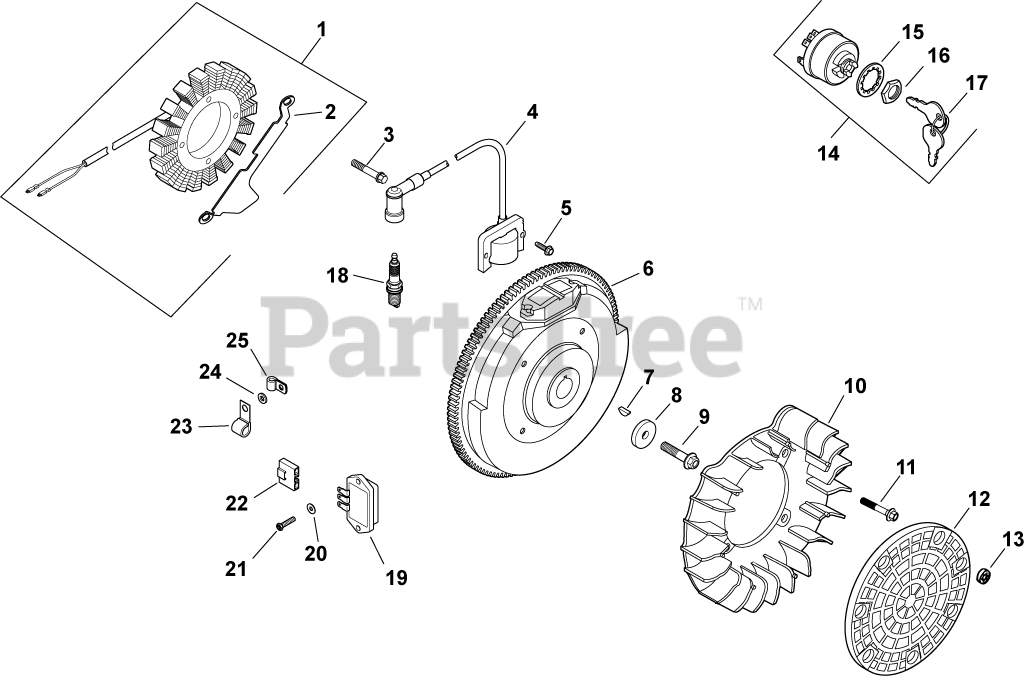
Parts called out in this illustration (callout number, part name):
1	KIT, 15 / 20 AMP STATOR
2	BRACKET, STATOR WIRE
3	SCREW, M5X0.8X25 - (#25086402S)
4	MODULE, IGNITION-USE 24 584 45-S
5	SCREW, FLG THD FRM M5X.8X20-(#25086399S)
7	KEY, 3/16" X 5/8"
8	WASHER, FLAT 13/32"
9	SCREW, FLG M10X1.5X45 - (#25086361S)
10	FAN (KM)-USE 24 157 15-S
11	BOLT, SHOULDER
12	SCREEN, GRASS-USE 24 755 171-S
14	SWITCH ASSY, KEY (KM)-USE 25 099 32-S
15	WASHER, INTERNAL TOOTH
16	NUT, KEY SWITCH
17	KEY, SET OF 2
18	PLUG, SPARK (STD)
20	WASHER, FLAT 3/16"
21	SCREW, PHL HD #11-16X7/8"
22	CONNECTOR, BODY (KM)-USE 25 155 41-S
23	CLIP, CABLE
24	WASHER, FLAT 1/4" (O.D. 1/2")
